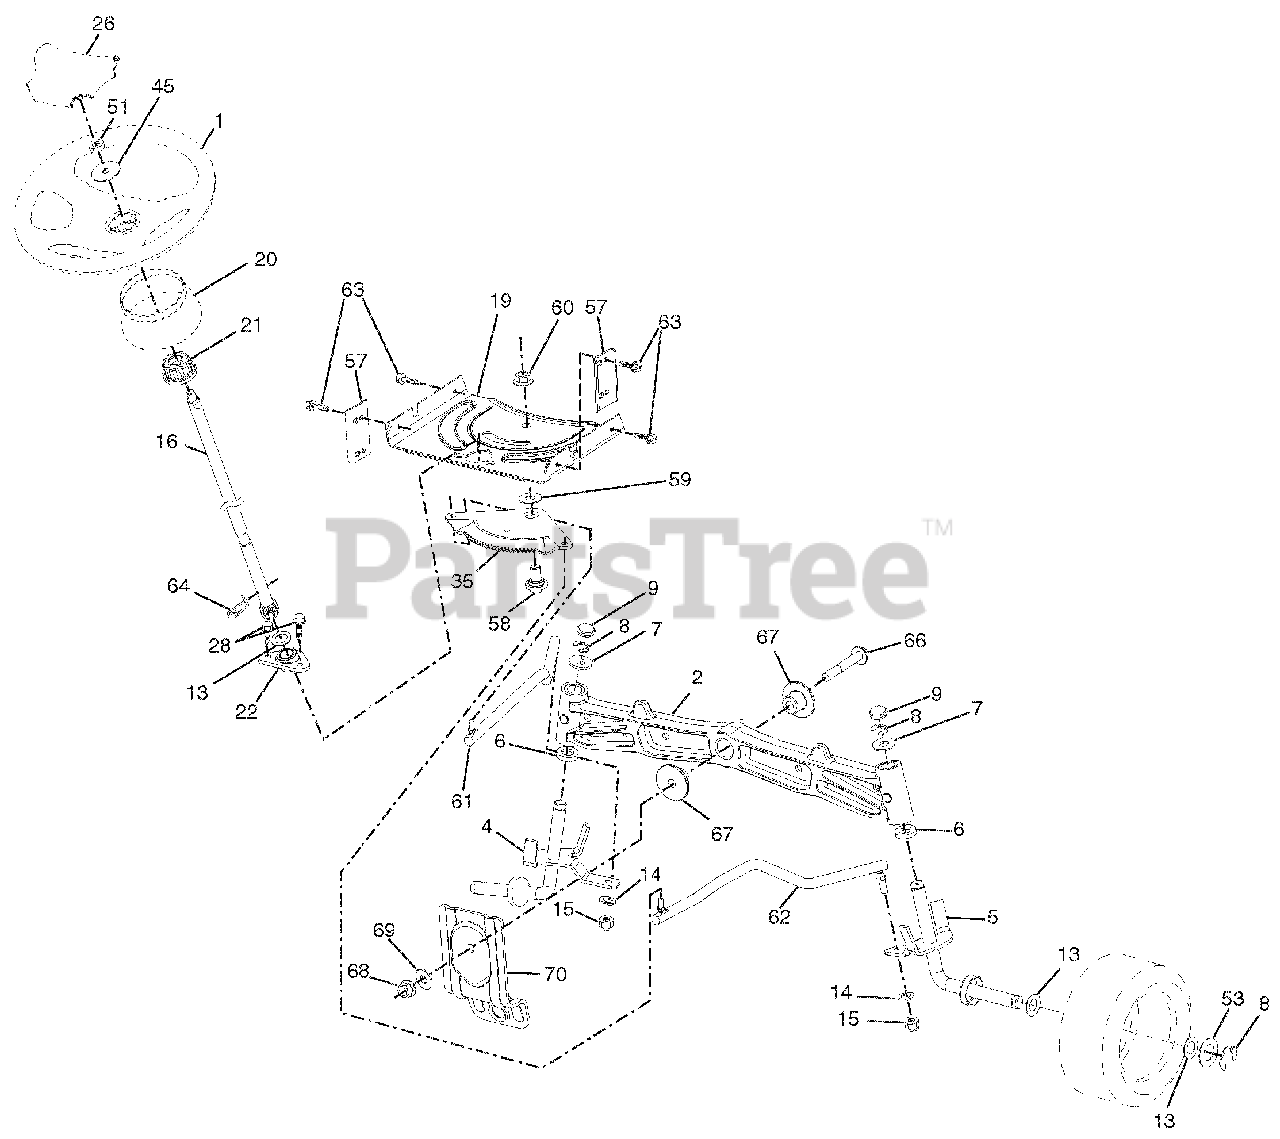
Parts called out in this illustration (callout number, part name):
1	WHEEL STEERING
2	AXLE.CAST IRON
4	SPINDLE.WELDED.LH.15"TEX
5	SPINDLE.WELDED.RH.15"TEX
6	WASHER.THRUST..75 X 1.230
7	WASHER.25/32 X 1-5/8 X 16GA.
8	RING.KLIP.#T5304-75
9	CAP.SPINDLE.FR.TOP.BLK.
13	WASHER.25/32 X 1 1/4 X 16 GA.
14	Washer, Lock 3/8
15	NUT.CROWNLOCK.3/8-24
16	SHAFT.STEER.3/4 TEX.NON-PLATED
19	PLATE.STEER.DDL.NLT/NGT
20	BOOT.STEERING.TEX ELITE.428
21	ADAPTER.WHEEL.STRG..760
22	STEERING SUPT. LOWER
26	CAP.WHL.STRG.HRS/SRS.BLACK
28	SCREW.HEXWSH THDR3/8-16X3/4.BL
35	GEAR SECTOR.PLATE.DDL.NLT/NGT
45	WASHER.9/16ID X 2-3/8OD.12GZIN
51	NUT.HEX.JAM.TOPLOCK.1/2-20 UNF
53	WASHER.HARDEN..793 X 1.637X060
57	BRACKET.UPSTOP.TEX
58	BOLT.SHOULDER.SECTOR.PIVOT.CFM
59	WASHER.THRUST.SECTOR.STEER.NLT
60	NUT.FLANGE LOCK.5/8-11
61	DRAGLINK.LH.BALLSTUD.DDL.
62	DRAGLINK.RH.BALLSTUD.DDL
63	SCREW.5/16-18X3/4.SMGML.TAP/BL
64	RETAINER.CLIP.SPRING.STEERING
66	BOLT.HEX.FGHD.7/16-14 X 3.SERR
67	BUSHING.PM.FRONT AXLE
68	NUT.LOCK.FLANGE.7/16-14.GR5
69	WASHER.1.5 X .505 X .118
70	BRACKET.DECK.SUSPENSION.FRONT
